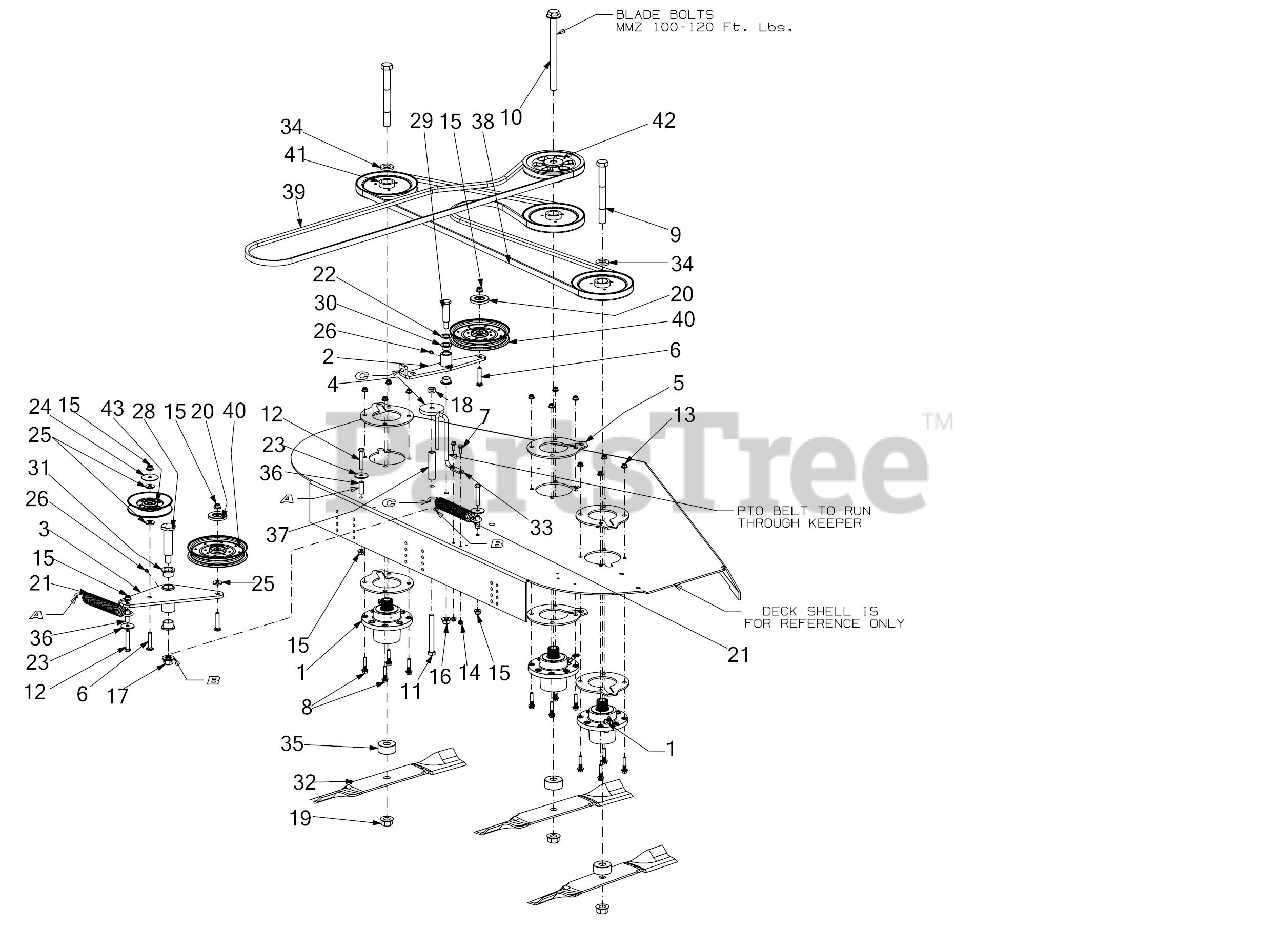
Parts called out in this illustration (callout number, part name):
1	SPINDLE ASSEMBLY
6	CARRIAGE BOLT 3/8-16 x 2
7	SCREW 1/4-20 x .75 GR5
8	BOLT 5/16-18 x 1.50 GR5
9	SCREW 3/4-16 x 7.00 GR5
10	SCREW 3/4-16 x 9.00 GR5
11	SCREW 1/2-13 x 4.5 GR 5
12	SCREW 3/8-16 x 2.25 GR5
13	FLANGE LOCK NUT 5/16-18
14	FLANGE LOCK NUT
18	HEX NUT CTR LK 1/2-13
19	HEX FLANGE NUT 3/4
20	PULLEY CAP
21	SPRING 1.25" DIA X 8.5" LONG
22	FLAT WASHER .793ID x 1.24OD x .060
23	FLAT WASHER .406X1.500X.105
24	HUB CAP WASHER .406 x 1.92 x .060
25	FLAT WASHER .406ID X1.0 OD
26	GREASE FITTING
28	SHOULDER SCREW 1.0 x 3.15
29	SHOULDER SCREW
30	FLANGE BEARING
32	21" BLADE (HI LIFT)
33	ROD KEEPER
34	SPACER .812 ID x .218 LG
39	V-BELT B SEC X 105.15
40	IDLER PULLEY
41	SPINDLE PULLEY 7"
42	PULLEY-7.01 OD x .75 ID
43	IDLER PULLEY 5.06 OD
